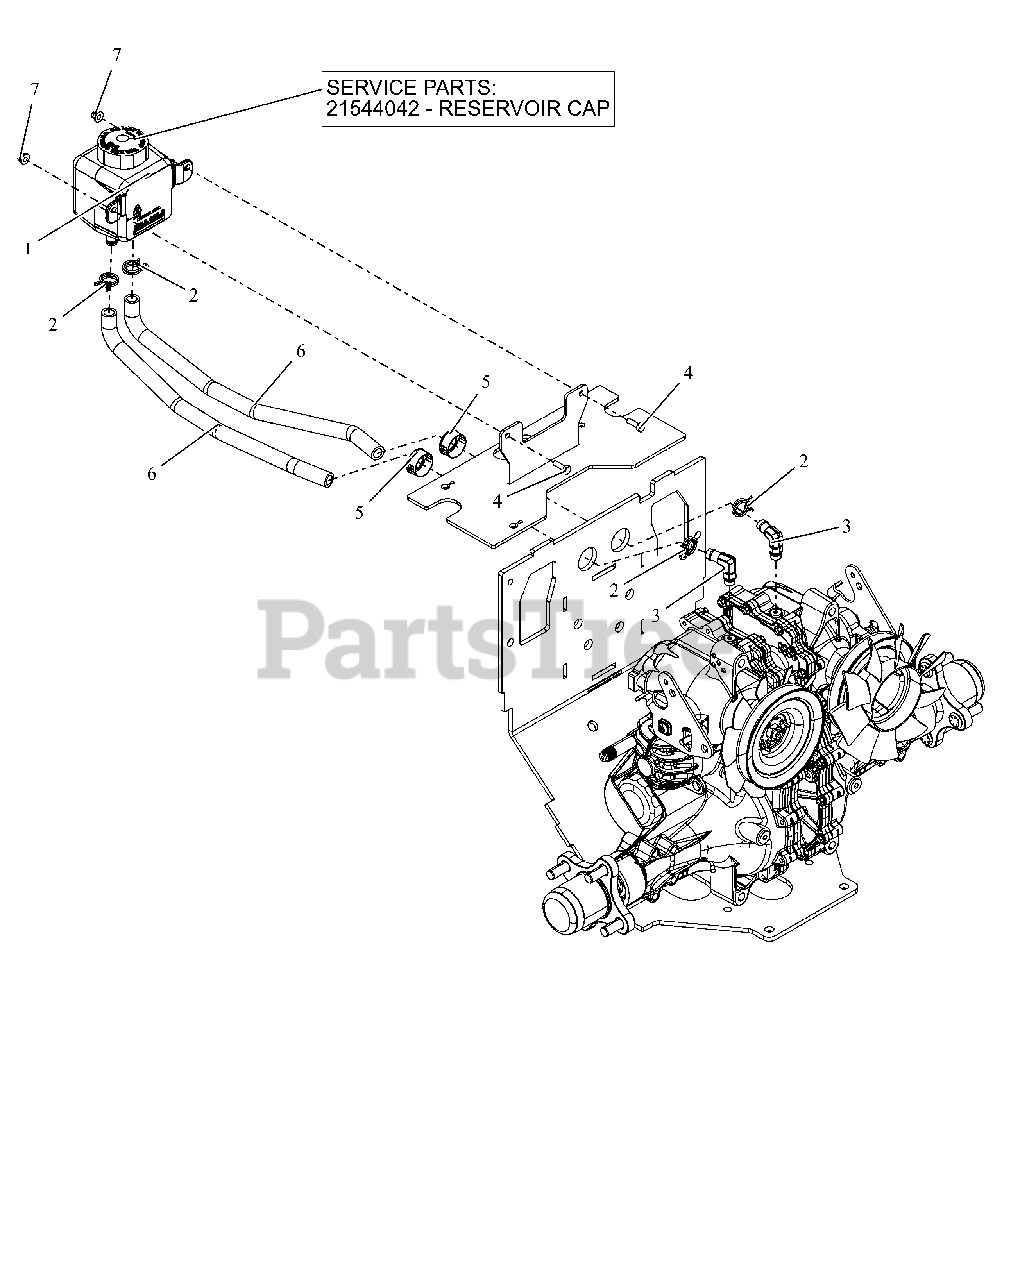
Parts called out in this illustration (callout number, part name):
1	TANK, HYDRO OVERFLOW 700 ML
1	CAP, HYDRO RESERVOIR REPLAC.
2	3/4 WIRE HOSE CLMP ZC
3	FTG,ORB 90? 7/16-20 - 1/2 BARB
4	BLT, HEX M6-1.0 X 20 G8.8 ZCC
5	BSHG, PANEL SNAP-IN 1.25" BLK
6	HOSE, HYDRO .50" X 17.125"
7	NUT,NYL-FLG M6-1.0 G8.8 ZCC
